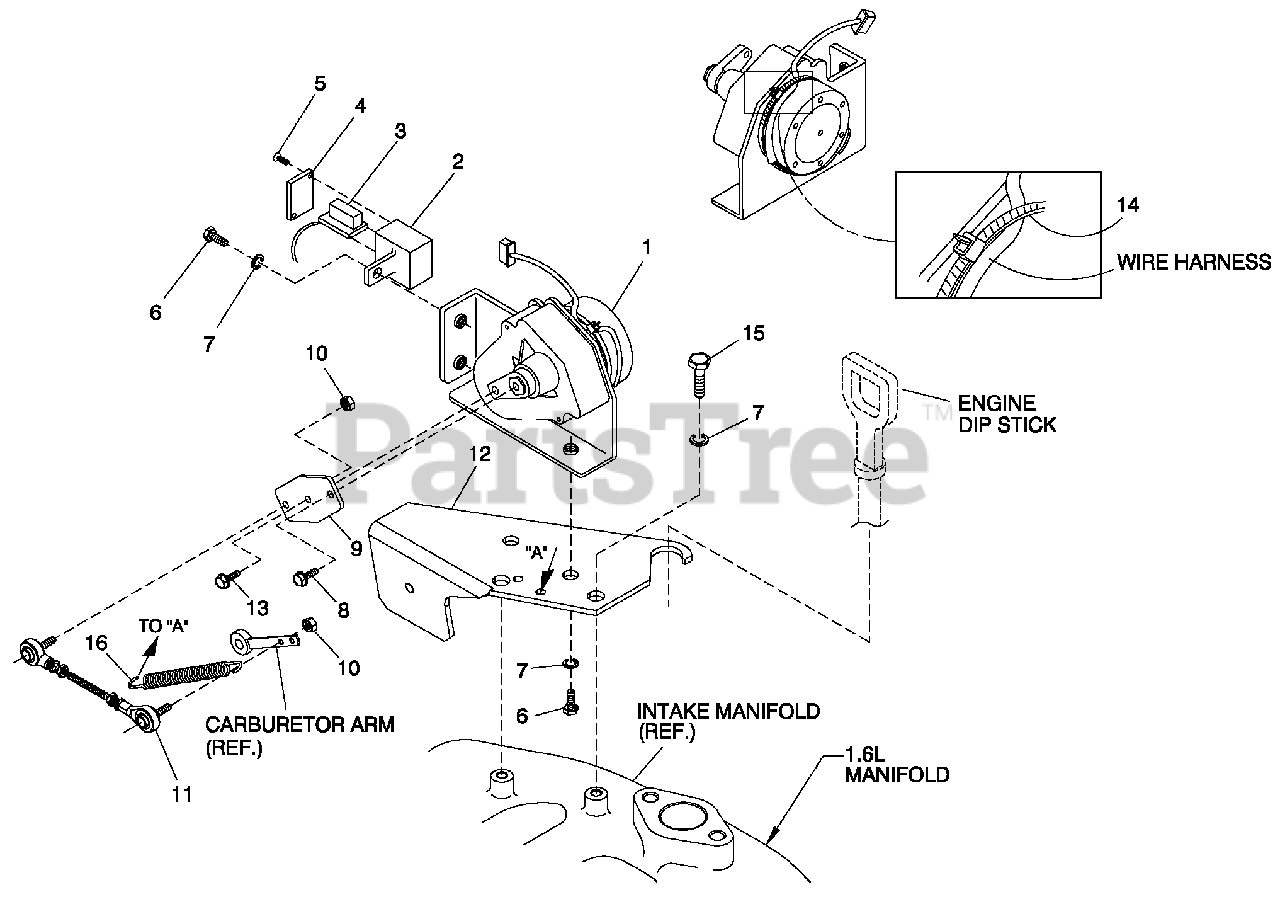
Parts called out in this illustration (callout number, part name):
1	ASM MOTOR STEPPER
2	HOUSING GOVERNOR CONNECTOR
3	CONNECTOR INTERFACE ASSEMBLY
4	COVER CONNECTOR HOUSING
5	SCREW FHM #2 X 5/8 SELF TAP
6	SCREW HHC M6-1.0X 10 G8.8
7	WASHER LOCK M6-1/4
8	SCREW PHM M3-0.5X 12MM
9	LEVER STEPPER MOTOR
10	NUT LOCK HEX #10-32 NYL INS
11	ASSY. CARBURETOR LINKAGE ROD
12	BRACKET STEPPER MOTOR COOLANT
13	SCREW TAP HWH #6-25 X 3/8 ZINC
14	TIE WRAP 7.4"X.19" BLK UL
15	SCREW HHC 1/4-20 X 1/2 G5
16	SPRING ANTI LASH
